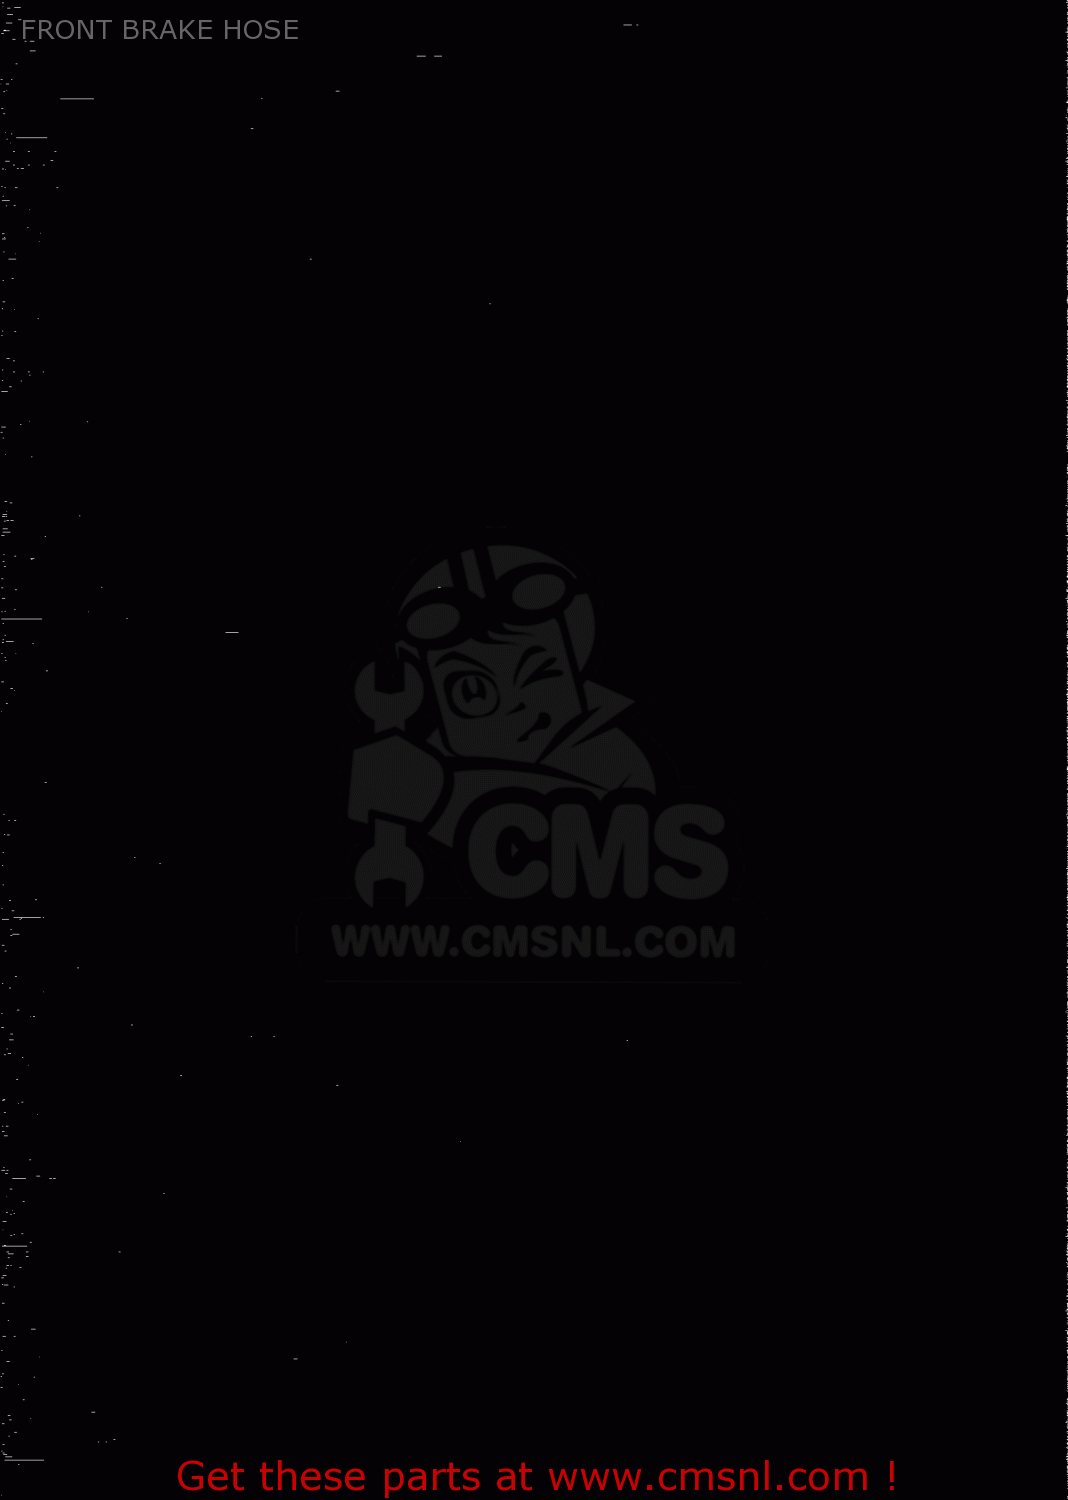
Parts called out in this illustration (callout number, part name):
1	BOOT
2	BOLT,UNION
3	WASHER
4	HOSE,BRAKE NO.1
5	JOINT,BRAKE HOSE
6	BOLT
7	LOCK WASHER
8	HOSE,FRONT BRAKE
9	CLAMP, HOSE RH
10	CLAMP, HOSE LH
11	BUSH,BRAKE HOSE GUIDE,NO.2
12	BOLT,UNION
13	WASHER
14	HOSE, ANTI NOSE
15	BOLT UNION
16	BOLT,UNION
17	WASHER
